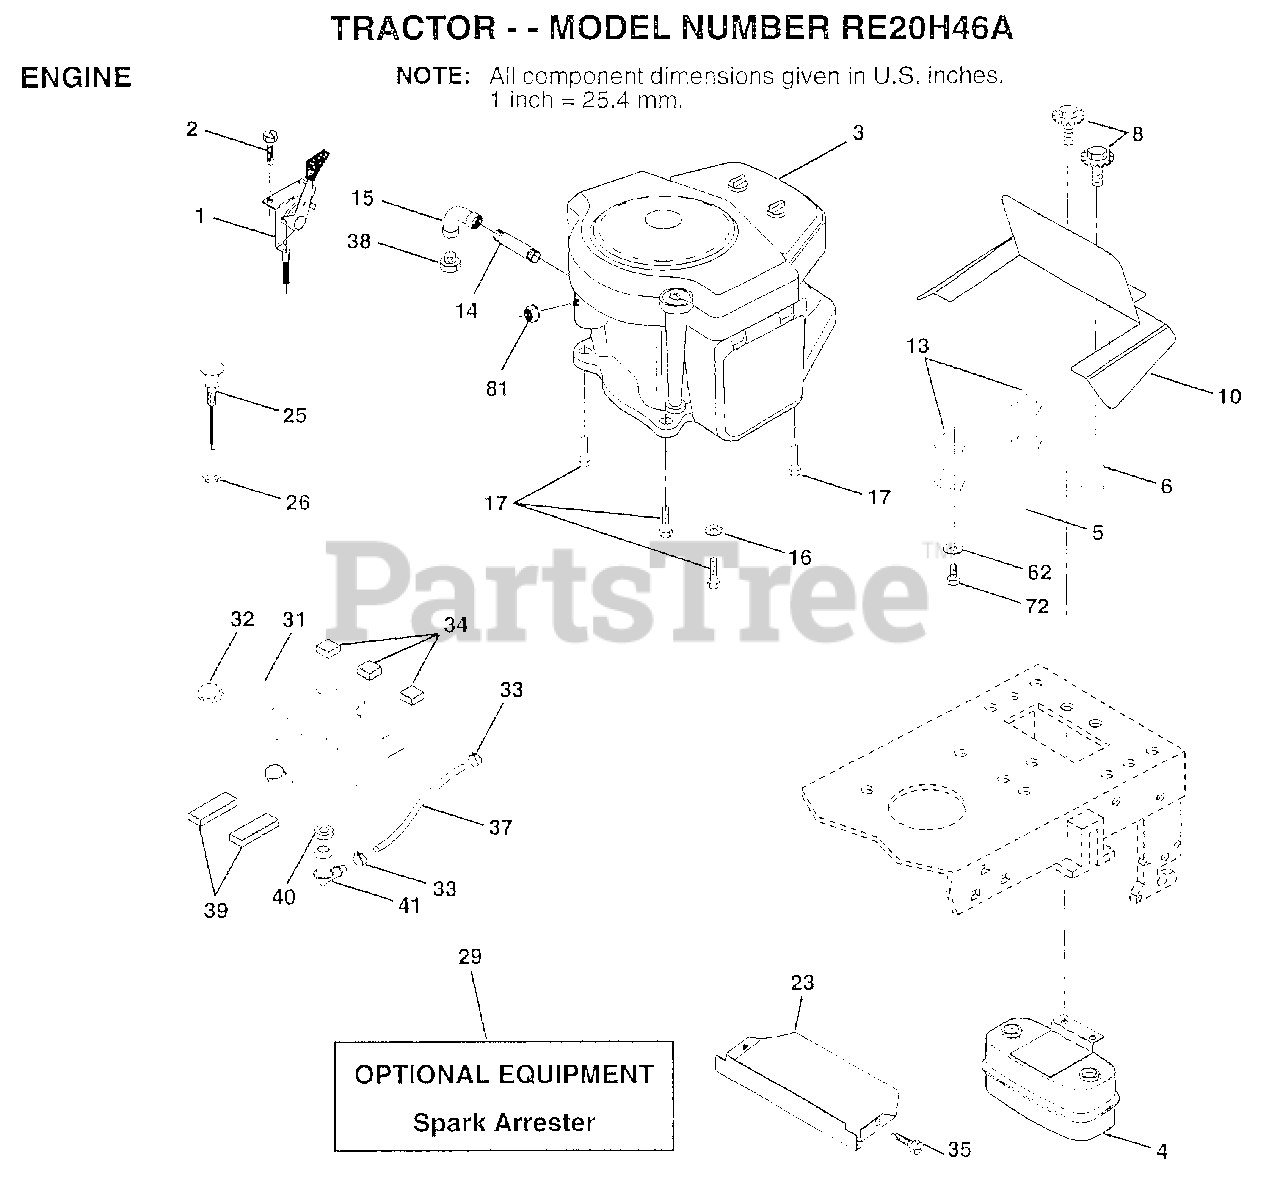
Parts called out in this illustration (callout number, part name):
1	CONTROL.TRTL.37
2	SCREW LT
4	MUFFLER.TW.LOTONE
5	TUBE MANIFOLD LH
6	TUBE MANIFOLD RH
8	BOLT.5/16-18.UNC
10	SHIELD.BROWNING
14	PIPE NIPPLE LT
15	ELBOW
16	LOCKWASHER
17	SCREW LT
23	SHIELD.BRN/DBR.GD
25	"CONTROL.CHOKE.51"""
26	"NUT,KEPS 3/8-24IM"
31	TANK FUEL REAR
32	CAP ASM FUEL
33	HOSE CLAMP
34	PAD-SPACER LT
35	SCREW
37	FUEL LINE T
39	PAD IDLER TI
40	BUSHING OUTLET T
41	STEM.TANK.FUEL
62	LOCKWASHER
72	SCREW
81	NUT
